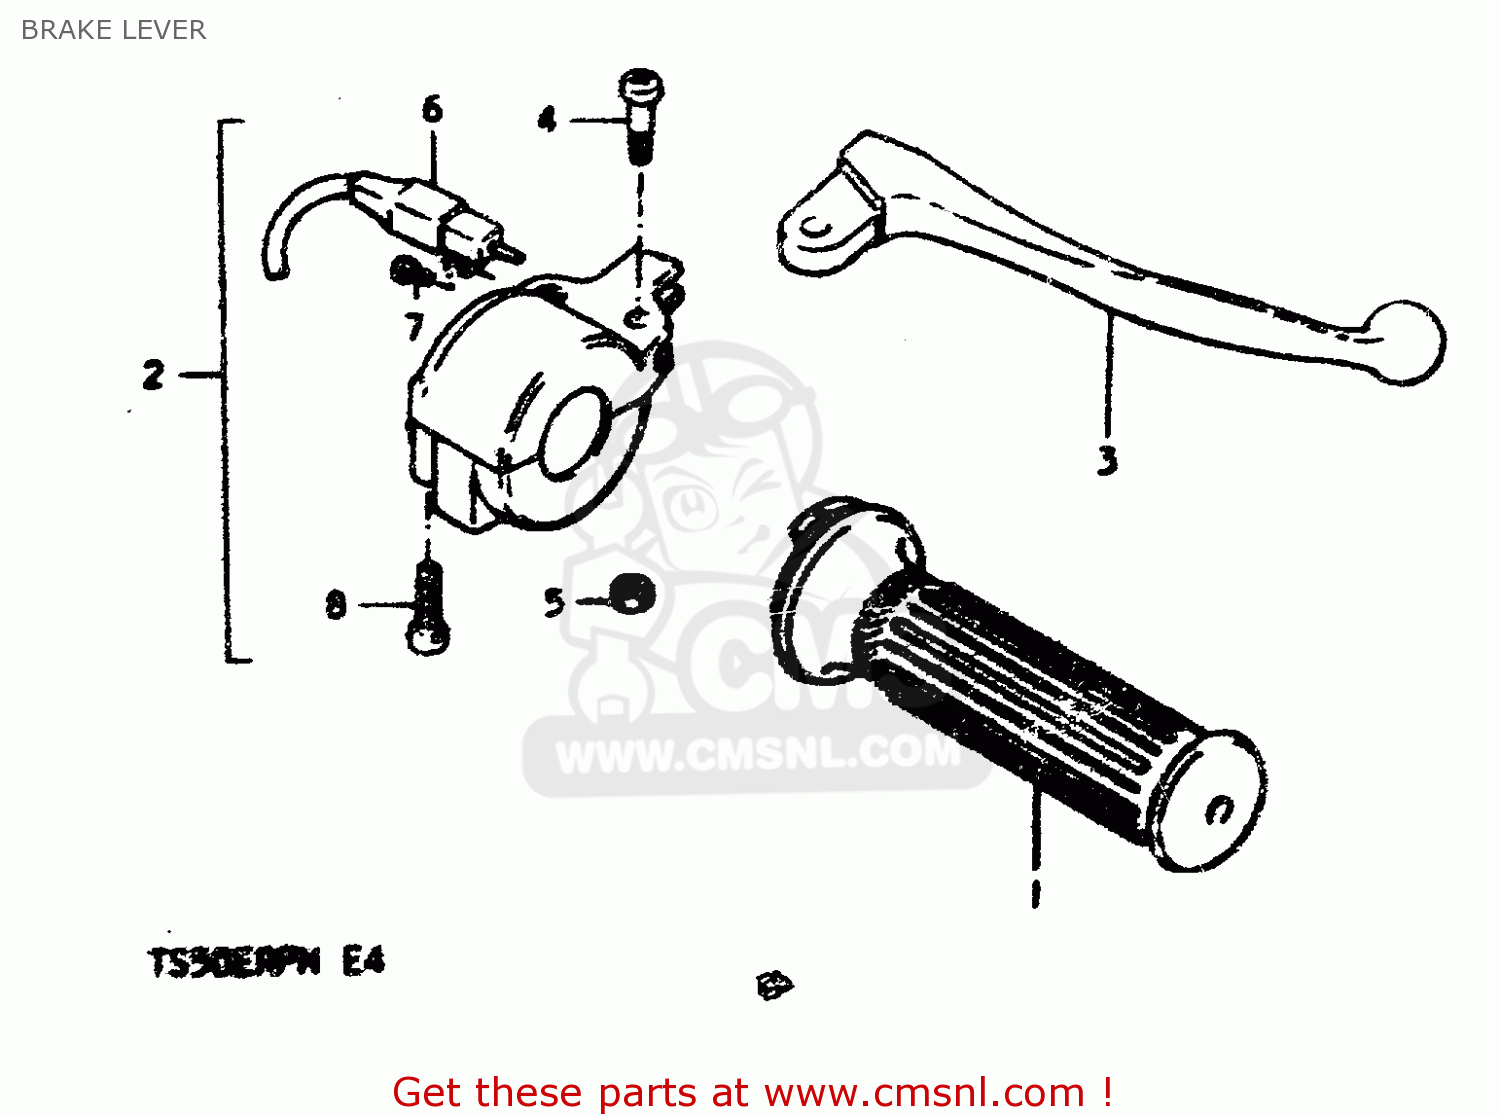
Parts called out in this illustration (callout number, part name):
1	GRIP,THROTTLE
2	BRAKE LEVER & SWITCH ASSY
3	LEVER
4	BOLT,LEVER
5	NUT,LEVER BOLT
6	WIRING HARNESS
7	SCREW
8	SCREW
